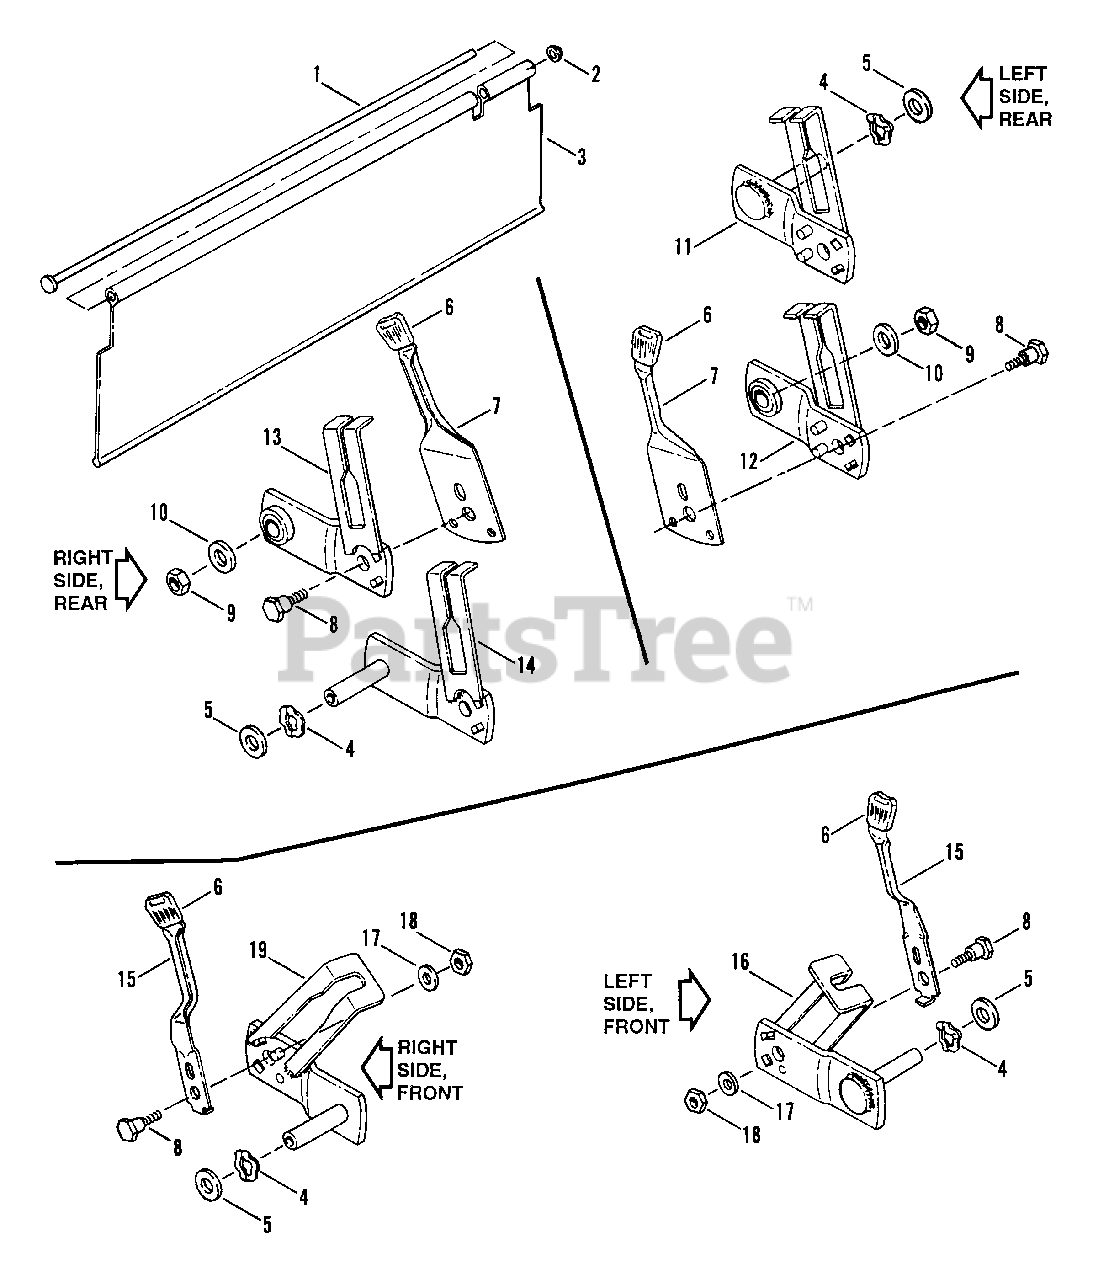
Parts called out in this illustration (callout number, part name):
1	ROD, Trail Shield
2	NUT, 5/16 Push
3	SHIELD, Trail
4	WASHER, 17/32 Wave
5	WASHER, 17/32" I.D. x 1" O.D. Flat
6	GRIP, Latch
7	ASSEMBLY, Height Adjusting Latch (Rear)
8	BOLT, 5/16-18 x 1-9/32" Shoulder
9	NUT, 7/16-20 Hex Center Lock
10	WASHER, 7/16 Flat
11	BRACKET, Wheel, Left Hand Rear
12	BRACKET, Wheel, Left Hand Rear
13	BRACKET, Wheel, Right Hand Rear
14	BRACKET, Wheel, Right Hand Rear
15	ASSEMBLY, Height Adjusting Latch (Front)
16	BRACKET, Wheel, Left Hand Front
17	WASHER, 5/16 Flat (Front)
18	NUT, 5/16-18 Hex Center Lock (Front)
19	BRACKET, Wheel, Right Hand Front
